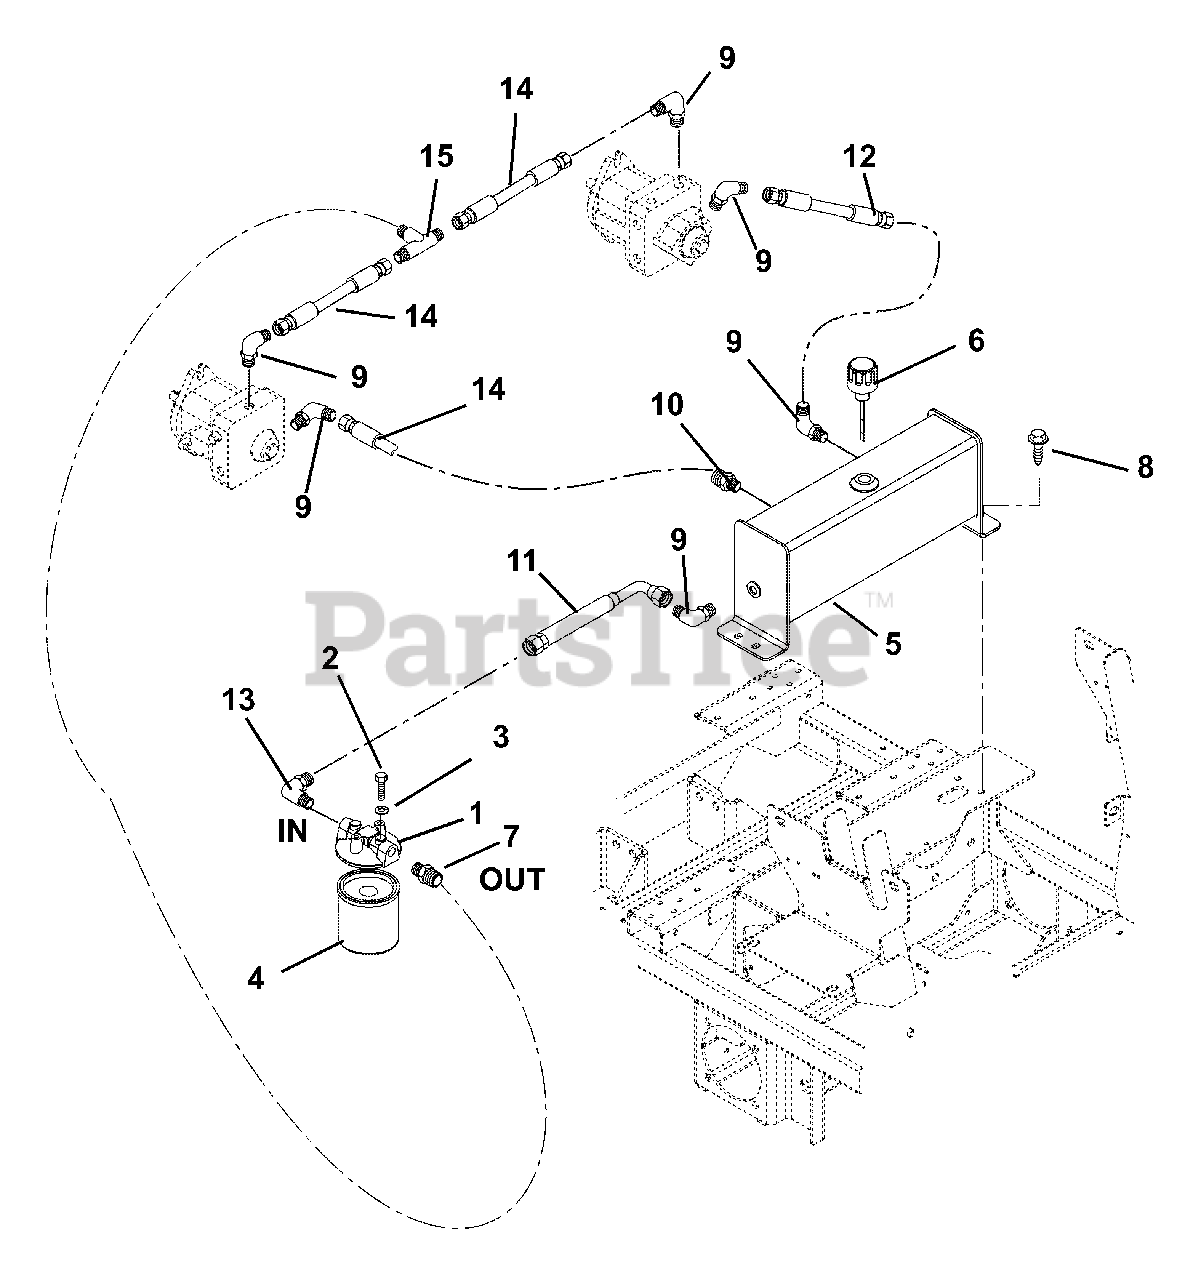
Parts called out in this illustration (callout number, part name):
1	FILTER HOUSING ZINGA ZAF11250
2	@BLT-HEX .25-20X.50 GR5 YWZC
3	@WSHR-LK .25X.062 REG YWZC
4	FILTER ELEMENT, ZINGA AE-25
5	WMT, HYDRAULIC TANK
6	BREATHER, DIPSTICK
7	ADPTR-HYD ST 1 1/16 "O" TO 3/4
8	@SCR-TAP .38-16X.75 HWH TR YWZ
9	ADPTR-HYD EL 3/4 "O" TO 3/4
10	ADAPTER, HYD ST 3/4 "O" TO 3/4
11	HOSE, HYD .50-16-0K F8J0-F8J9
12	HOSE, HYD .50-10-0K F8J0-F8J0
13	ADPT,EL 90DEG .75-16MX1.06-12M
14	HOSE, HYD .50-5-0K F8J0-F8J0
15	FTG HYD TEE M8J-F8J-M8J
